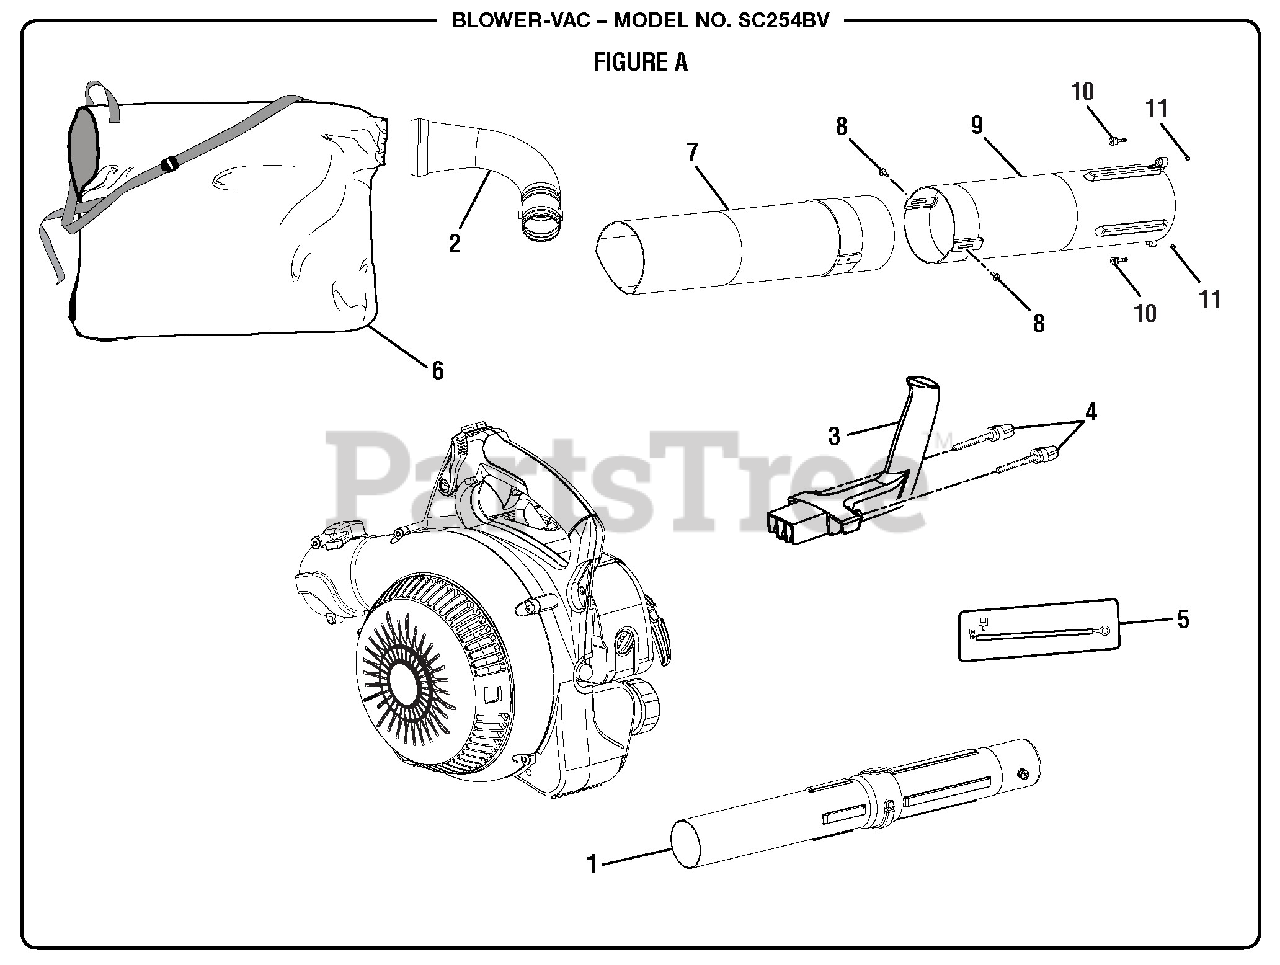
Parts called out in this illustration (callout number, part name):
1	Upper and Lower Blower Tube Assembly
2	Vacuum Bag Adaptor
3	Vacuum Handle
4	Vacuum Handle Knob
5	Ground Wire Kit
6	Vacuum Bag w/Shoulder Strap
7	Lower Vacuum Tube
8	Screw (10-14 x 1/2 in., T25 Torx T.F.)
9	Upper Vacuum Tube
10	Screw (1/4-20 x 3/4 in., Hex Hd.)
11	E-Ring (Retaining Ring)
